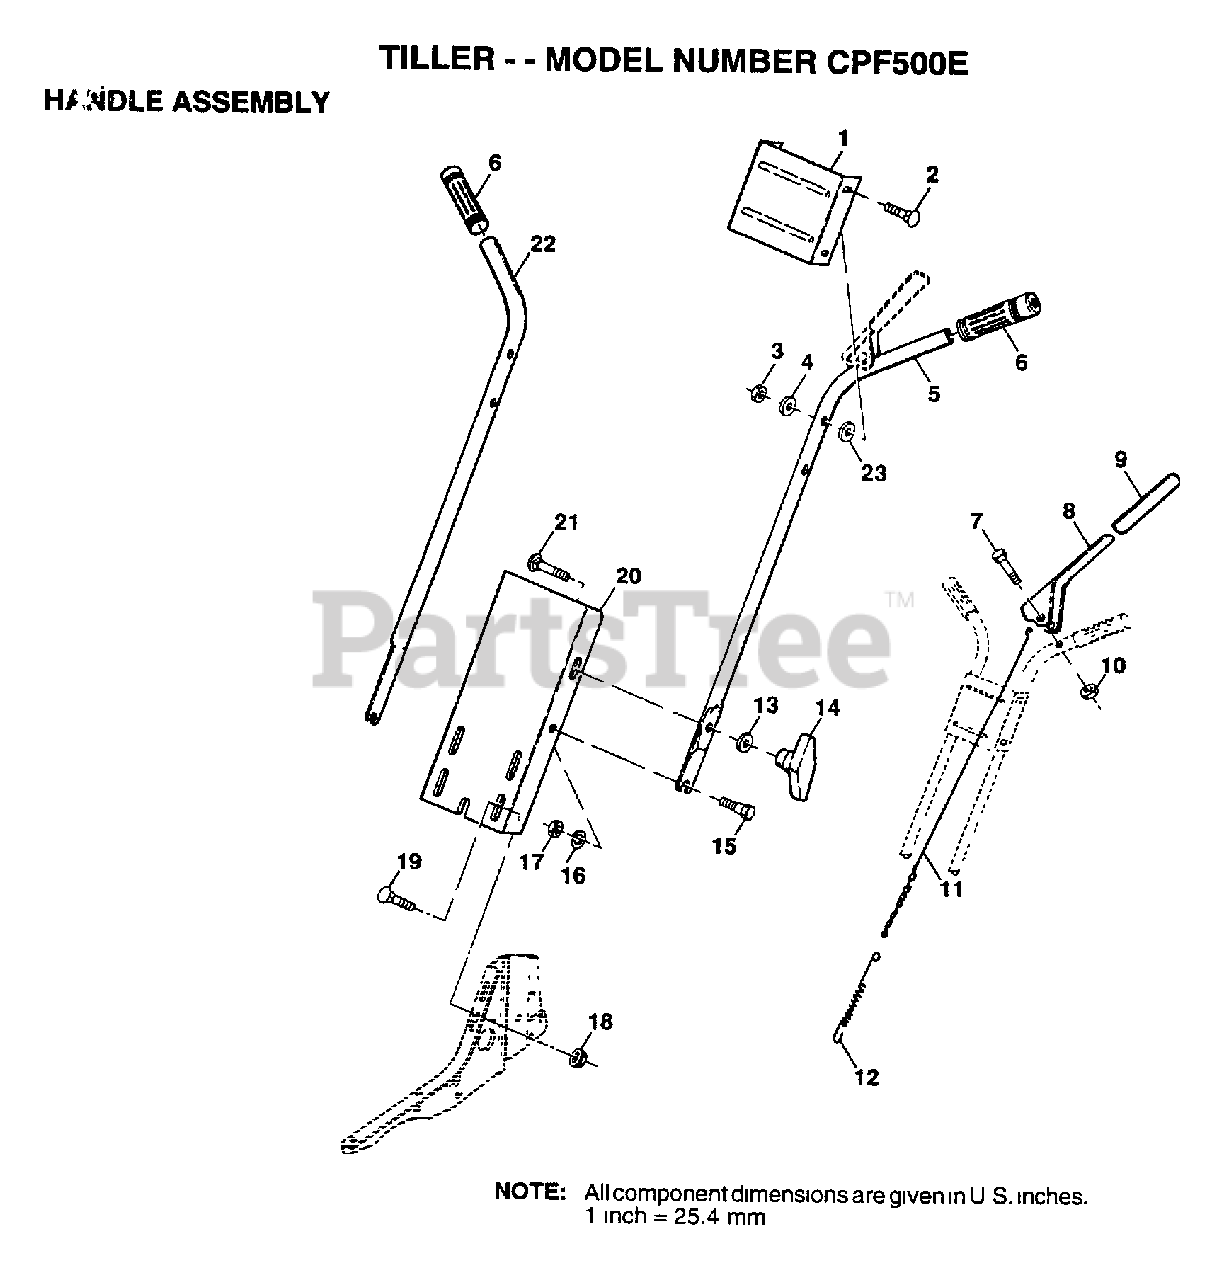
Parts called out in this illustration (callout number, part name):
1	BRACKET.HANDLE
2	BOLT
4	WASHER
6	GRIP NUB DOUBLE
7	BOLT.HEX.5/16-1.5
9	GRIP T
12	SPRING EXT TI
13	WASHER
14	KNOB HANDLE
16	LOCKWASHER
17	NUT.HEX.5/16-18
18	NUT
19	BOLT
21	BOLT CRT
23	WASHER
